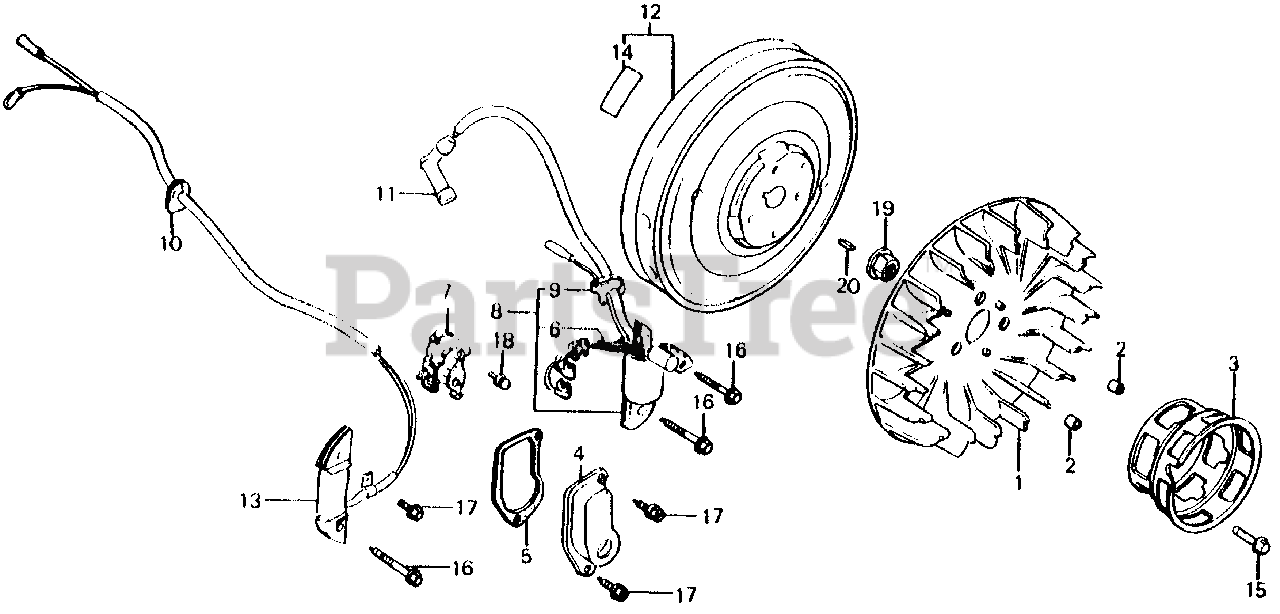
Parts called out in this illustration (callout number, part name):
1	FAN, COOLING
2	COLLAR, FAN
3	PULLEY, STARTER
4	COVER, POINTS
5	GASKET, POINT COVER
7	POINTS ASSY.
8	COIL ASSY., IGNITION (NOT AVAILABLE)
9	GROMMET, WIRE
10	GROMMET, WIRE
11	CAP ASSY., NOISE SUPPRESSOR
12	FLYWHEEL (POINT)
13	COIL ASSY., BACK-UP
14	MARK, FLYWHEEL CAUTION
15	BOLT, FLANGE (6X16)
16	BOLT, FLANGE (6X32)
17	BOLT, FLANGE (5X10)
18	SCREW-WASHER (5X12)
19	NUT, SPECIAL (14MM)
20	KEY, SPECIAL WOODRUFF (25X18)
